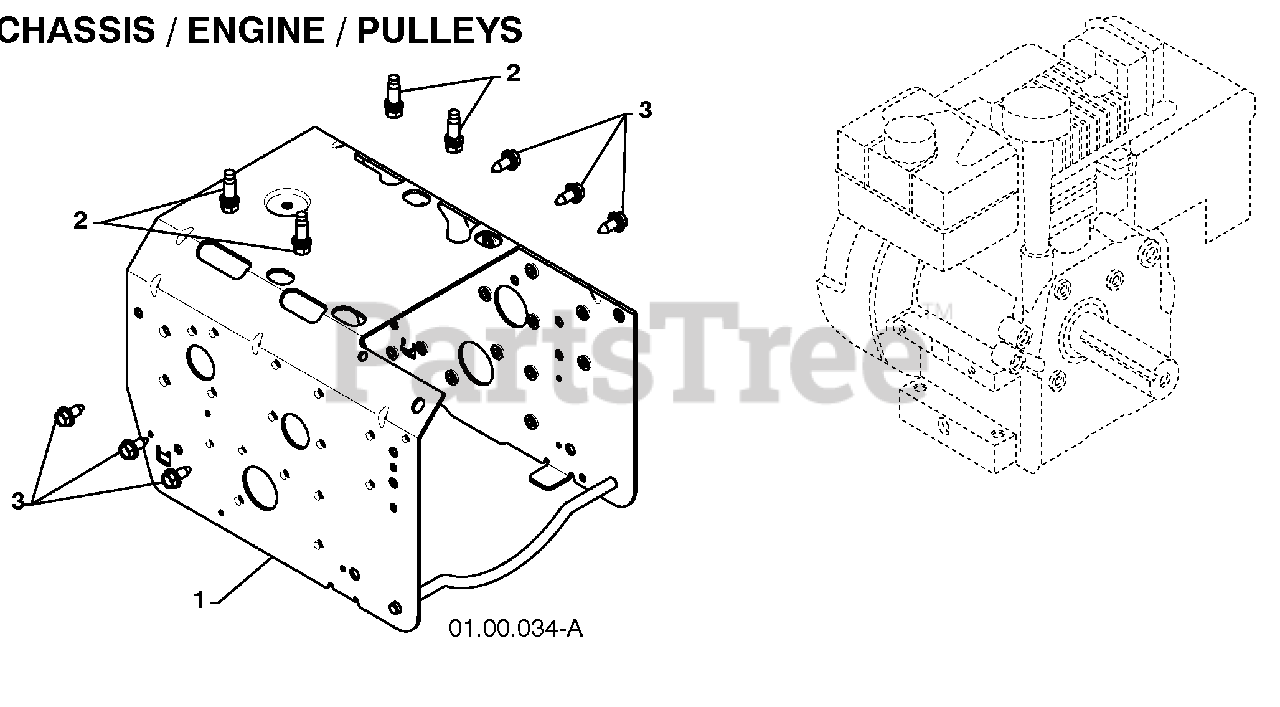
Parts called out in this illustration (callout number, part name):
1	FRAME
2	BOLT 3/8-16
3	SCREW 5/16-18 X .750
